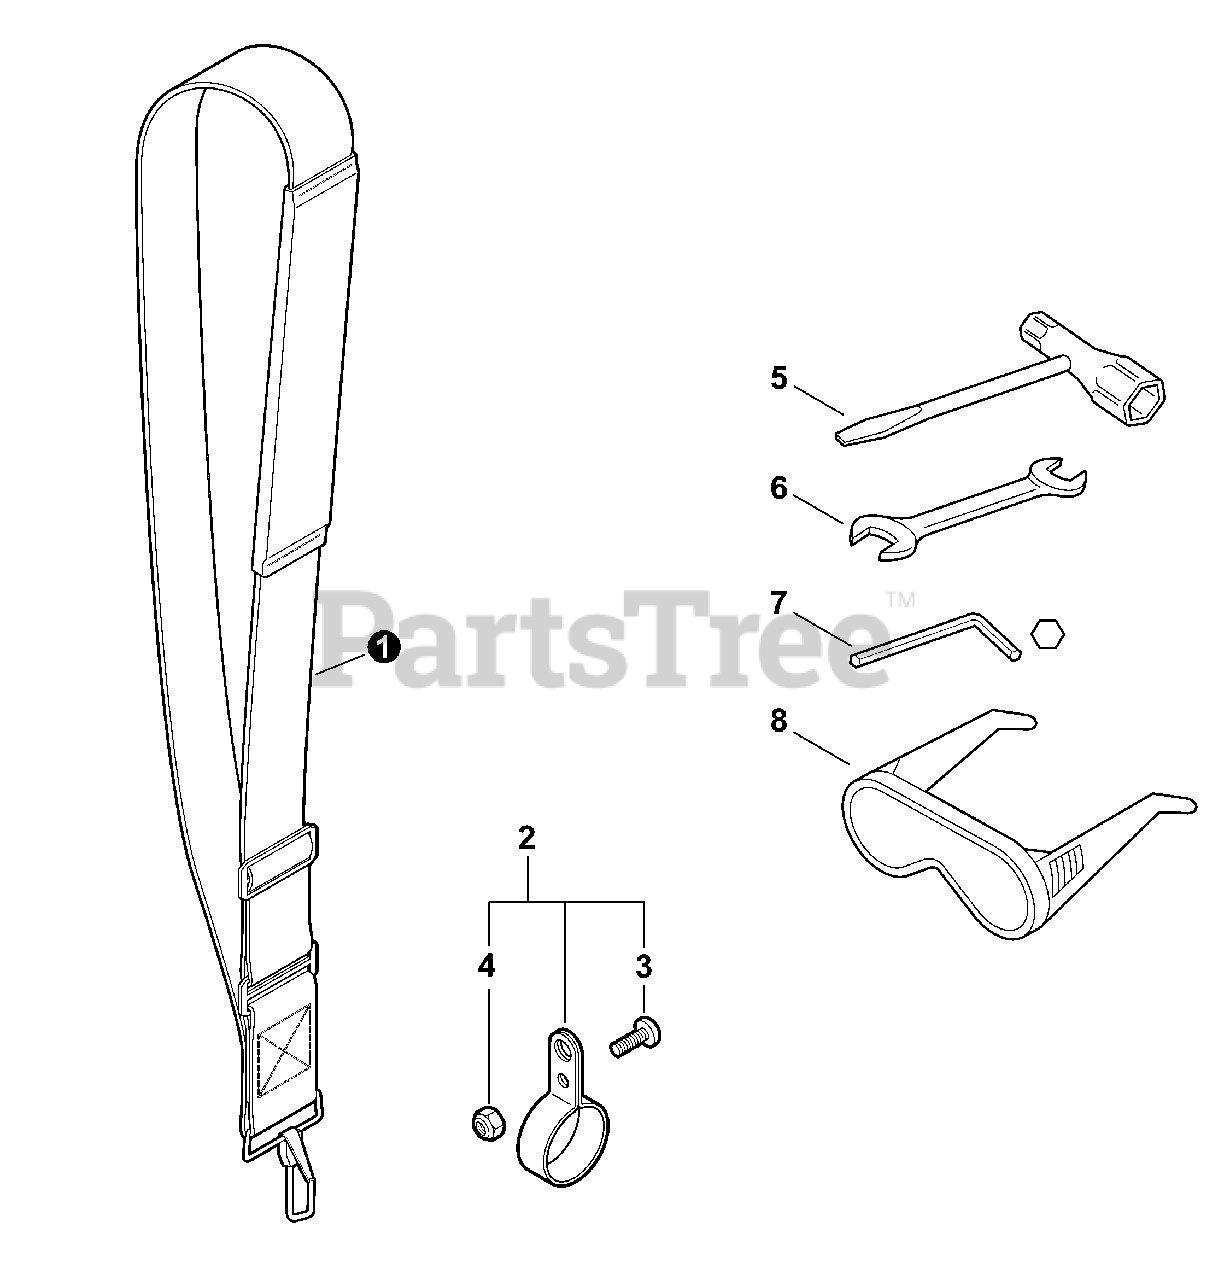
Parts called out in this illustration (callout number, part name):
1	STRAP ASSY, SHOULDER
2	HANGER KIT
3	SCREW
4	NUT, LOCK 10-24 UNC
5	T-WRENCH 10×19 MM
6	SPANNER 8×10
7	WRENCH, ALLEN 4 MM
8	GLASSES, SAFETY
